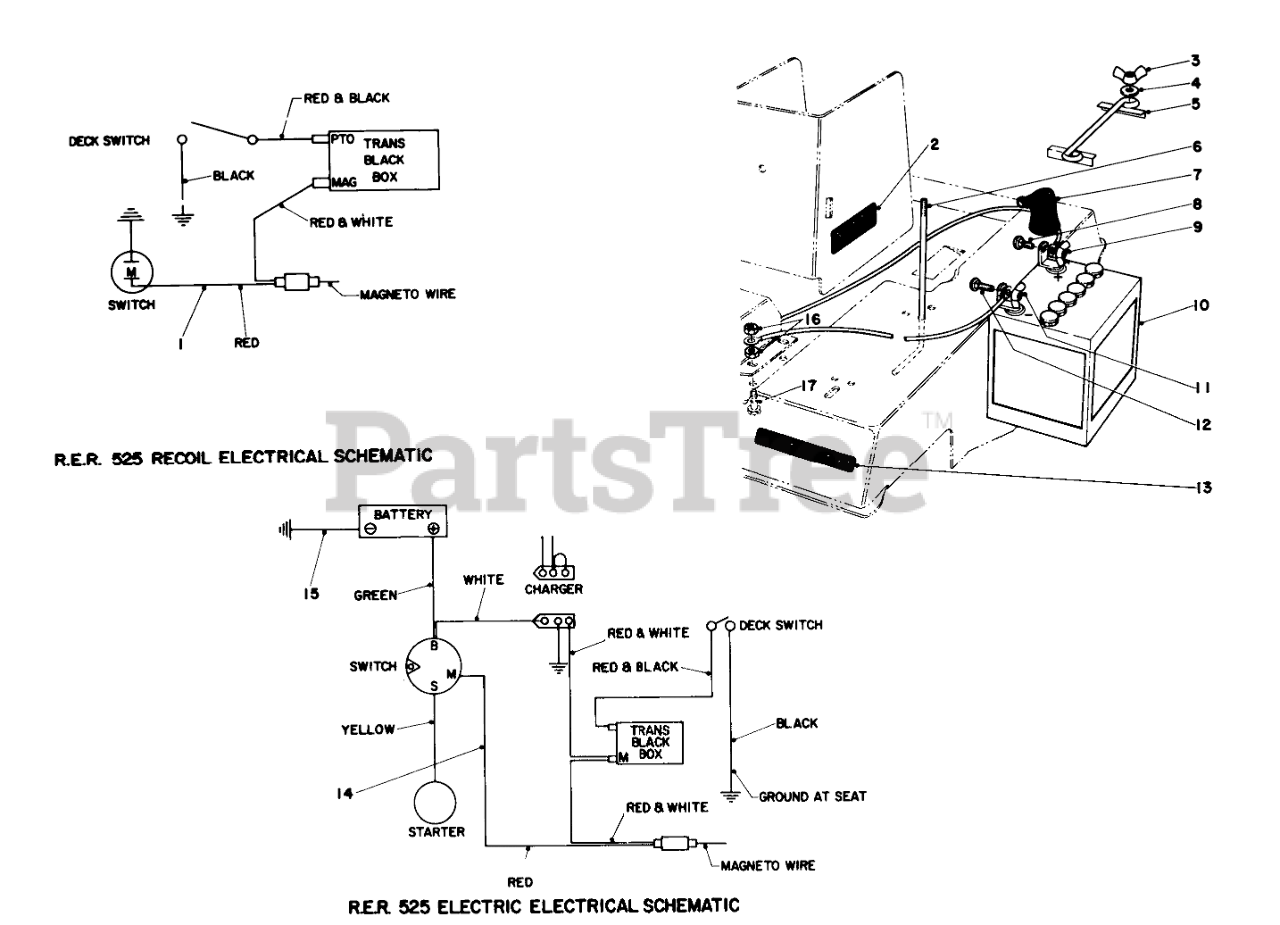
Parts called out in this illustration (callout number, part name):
1	Wire Harness (Model 56005)
2	Decal (Model 56010)
3	Wing Nut
4	WASHER-FLAT
5	Clamp
6	Battery Bolt
7	BATTERY BOOT
8	BOLT-CARR
9	NUT-HEX
10	Battery
11	NUT-HEX
12	BOLT-CARR
13	Decal (Model 56150)
14	Wire Harness (Model 56010)
15	Wire Assembly
16	NUT-LOCK, CONE
17	SCREW-HH
